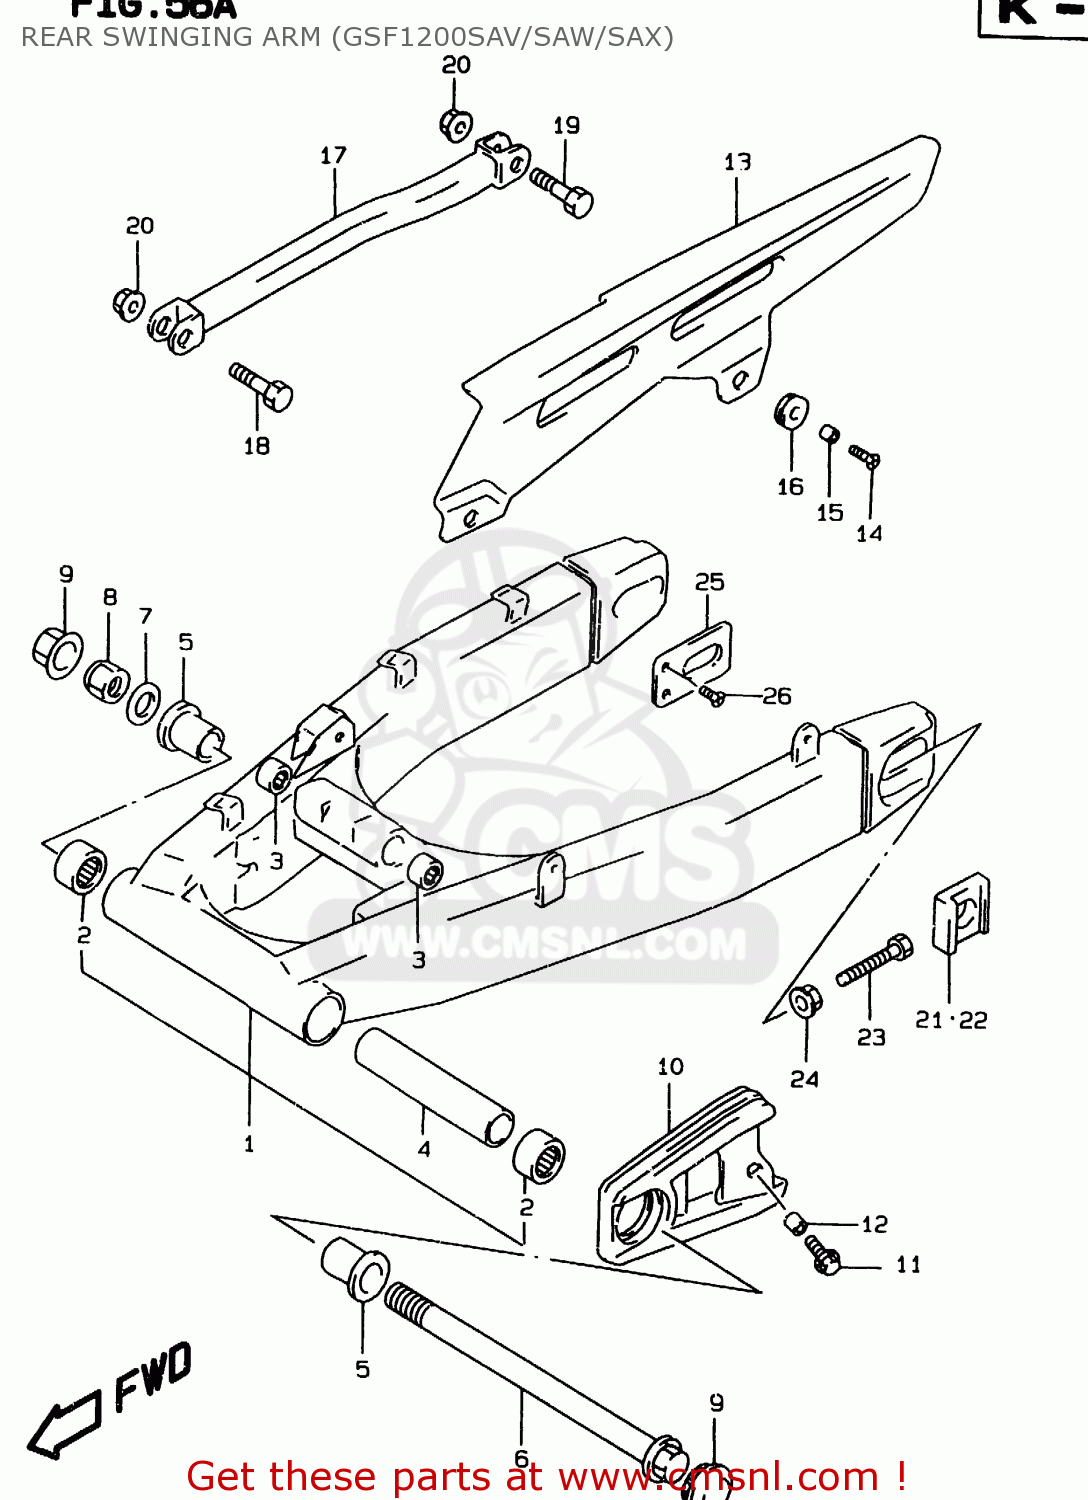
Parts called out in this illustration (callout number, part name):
1	SWING ARM ASSEMBLY,REAR
2	BEARING(25X33X35)
3	BEARING(17X24X25)
4	SPACER,RR SWGARM PIVOT CTR
5	SPACER,RR SWGARM PIVOT BERRING
6	SHAFT,RR SWINGINGARM PIVOT
7	WASHER(18.5X28X2.6)
8	NUT
9	CAP,FRAME PIVOT
10	BUFFER,CHAIN TOUCH DEFENSE
11	BOLT 6X20,WITH PLAIN WASHER
12	SPACER(6.5X10X7)
13	CASE,CHAIN
14	SCREW (6X16)
15	SPACER(6.2X8.3X6.1)
16	CUSHION
17	TORQUELINK,RR
18	BOLT(10X39)
19	BOLT(10X34)
20	NUT
21	WASHER,CHAIN ADJUSTER
22	WASHER,CHAIN ADJUSTER
23	BOLT(8X50)
24	NUT
25	PLATE,RR SWING ARM BRKT
26	SCREW 6X10
